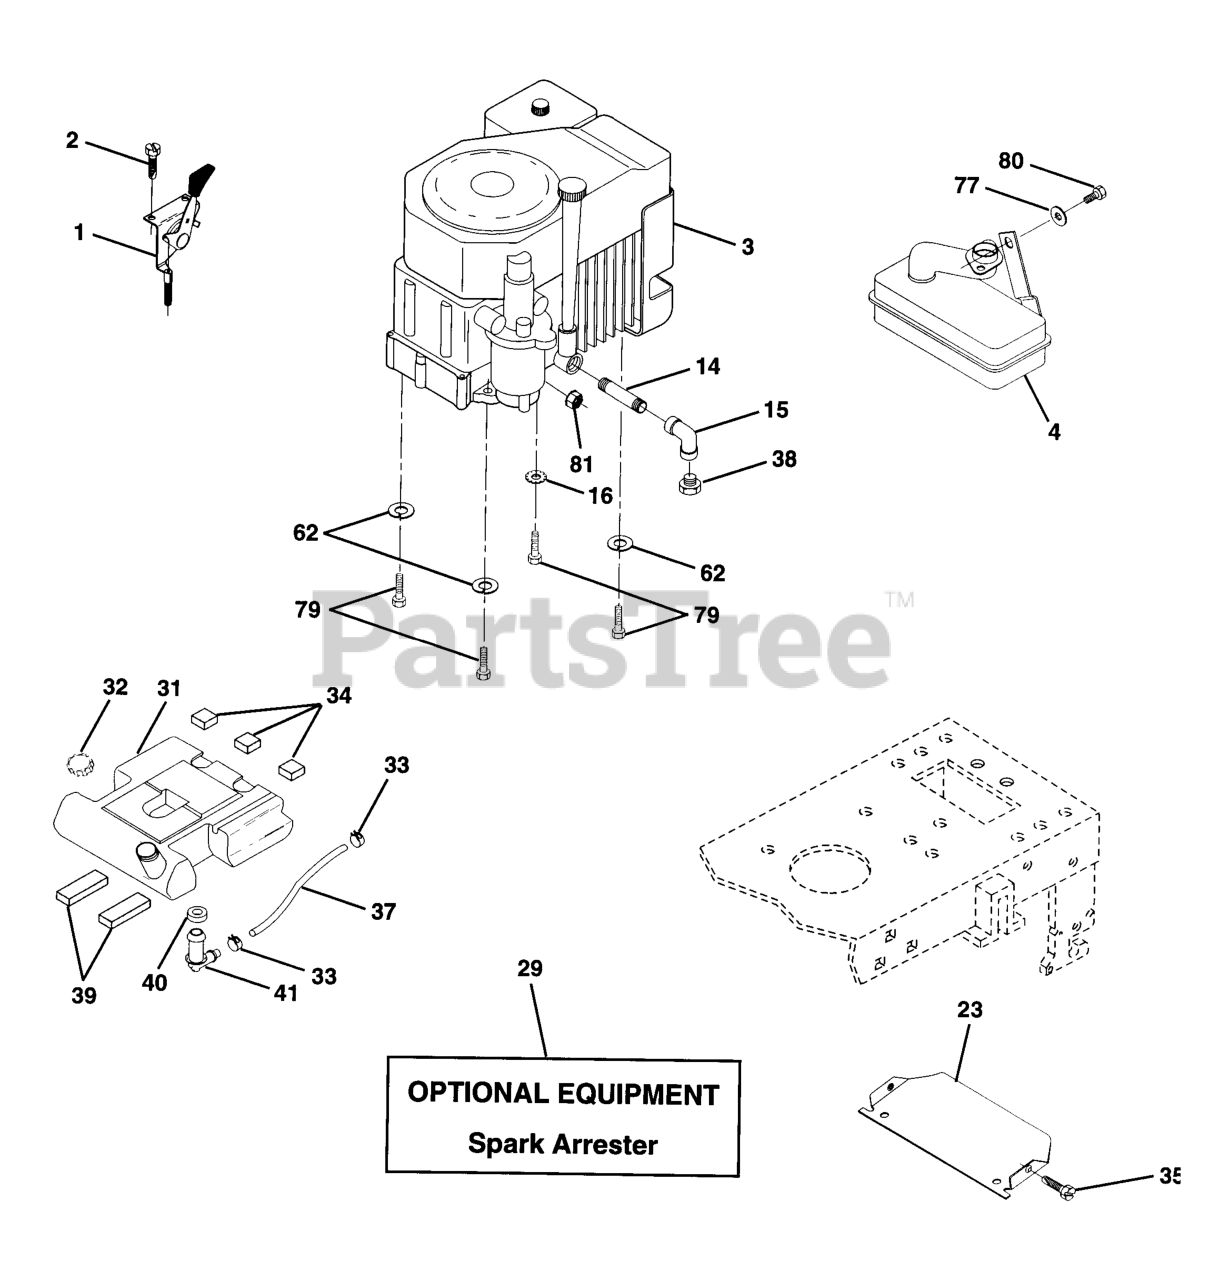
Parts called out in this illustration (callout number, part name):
1	CONTROL SWITCH 27 LH
2	SCREW LT
4	MUFFLER LT 12.5
14	Nipple Pipe 3/8 Npt X 3-1/2
15	ELBOW
16	LOCKWASHER
23	SHIELD HEAT
29	KIT.SPARK ARRESTOR 794945 B&S
31	FUEL TANK
32	FUEL CAP
33	HOSE CLAMP
34	PAD-SPACER LT
35	SCREW.THDROL.5/16-18X3/4.TTY
37	HOSE T
38	Plug Oil Drain (Order From Engine Manufacturer)
39	PAD IDLER TI
40	BUSHING OUTLET T
41	STEM FUEL TANK
62	WASHER.LOCK.HVY.HLCL.SPR.5/16
77	WASHER
79	BOLT, HEX
80	Bolt Hex Hd. 5/16-18unc x 1/2
81	NUT FLANGE 1/4-20 STARTER NUT
